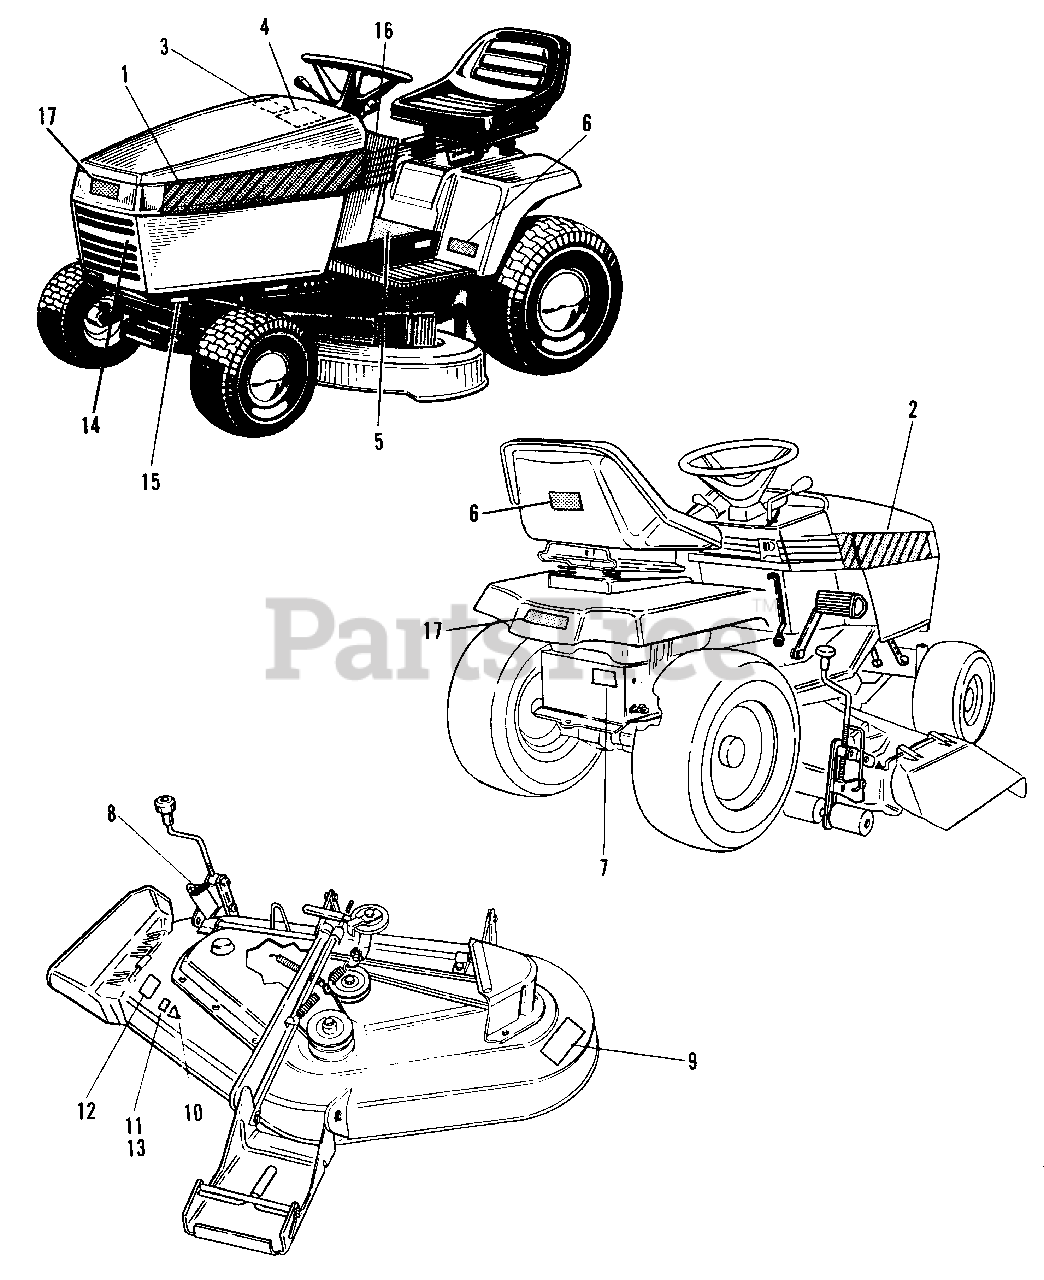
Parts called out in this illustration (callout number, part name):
1	DECAL, Hood, L.H., AGCO Allis, 16H
1	DECAL, Hood, L.H., AGCO Allis, 14H
1	DECAL, Hood, L.H., AGCO Allis, 12.5H
1	DECAL, Hood, L.H., AGCO Allis, 15G
2	DECAL, Hood, R.H., AGCO Allis, 16H
2	DECAL, Hood, R.H., AGCO Allis, 14H
2	DECAL, Hood, R.H., AGCO Allis, 12.5H
2	DECAL, Hood, R.H., AGCO Allis, 15G
3	DECAL, Paint
4	DECAL, Belt, Blade
5	DECAL, Operating Inst.
6	DECAL, USA Logo
7	DECAL, Release Valve (Hydrostatic Units only)
8	DECAL, Mower Height
9	DECAL, Danger (Hand Under Deck)
10	DECAL, OPEI
11	DECAL, Cutting Width, 38"
12	DECAL, Danger (Chute in Place)
13	DECAL, Cutting Width, 44"
14	DECAL, AGCO Allis Badge
15	I.D. PLATE
16	DECAL, Choke, Dash (15 HP Briggs & Stratton only)
16	DECAL, Battery
